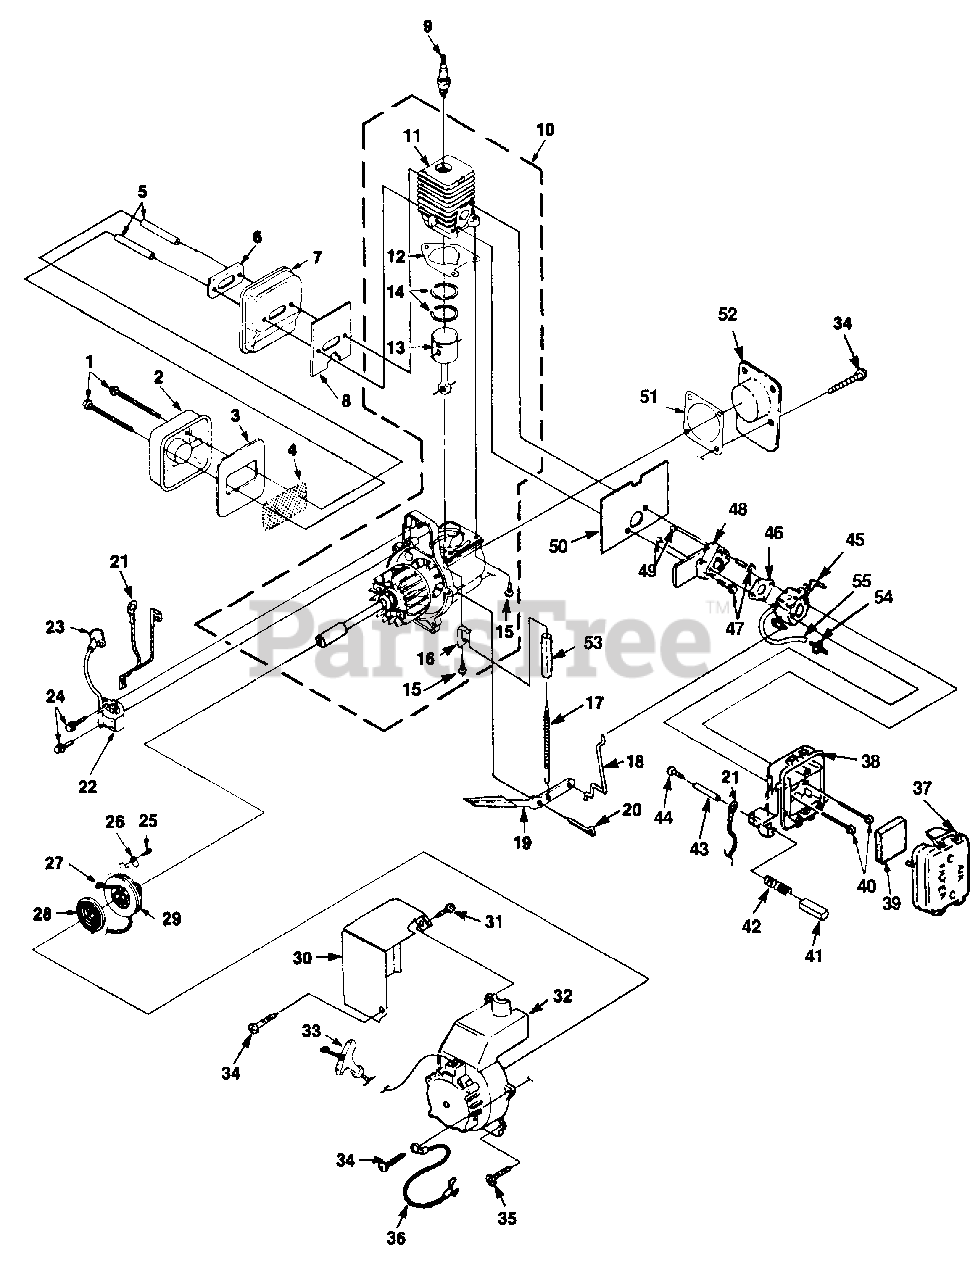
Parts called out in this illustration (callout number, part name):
1	SCREW- Sems Hex Hd. (10-24 x 3")
2	COVER- Muffler
3	BAFFLE- Muffler
4	SCREEN- Spark
5	SPACER- Muffler
6	PLATE- Reinforcing
7	BODY- Muffler
8	GASKET- Muffler
9	SPARK PLUG
10	SHORT BLOCK
11	CYLINDER
12	GASKET- Cylinder
13	PISTON & ROD
14	RING- Piston
15	SCREW-Thd. Form
16	BRACKET- Governor
17	SPRING- Extension
19	VANE- Governor
20	PIN- Cotter
21	LEAD- Electrical
22	MODULE- Ignition
23	TERMINAL- Hi Tension
24	SCREW- Thd. Form (8-32 x 1")
25	SCREW- Thd. Form (#10 x 1/2")
26	BRACKET- Retaining
27	ROPE- Starter
28	SPRING & CONTAINER
29	PULLEY- Starter
31	SCREW- Thd. Form (#10 x 1/2")
32	HOUSING w/EYELET
33	GRIP- Starter
34	SCREW- (10-24 x 3/4")
35	SCREW- (10-24 x 1 1/4")
36	LEAD- Ground
37	COVER- Air Filter
38	BOX- Air Filter
39	FILTER- Air
40	SCREW- Truss Hd. (10-24 x 2 1/2")
41	BUTTON- Stop
42	SPRING- Compression
44	SCREW- Pan Hd. (6-19 x 3/4")
45	CARBURETOR
46	GASKET- Carburetor
47	SCREW- Thd. Form (10-24 x 1")
48	DAM- Heat
49	NUT- (10-24)
50	GASKET- Heat Dam
51	GASKET- Crankcase Cover
52	COVER- Crankcase
54	FITTING- Fuel Inline
55	TUBING- Rubber (5 1/2")
